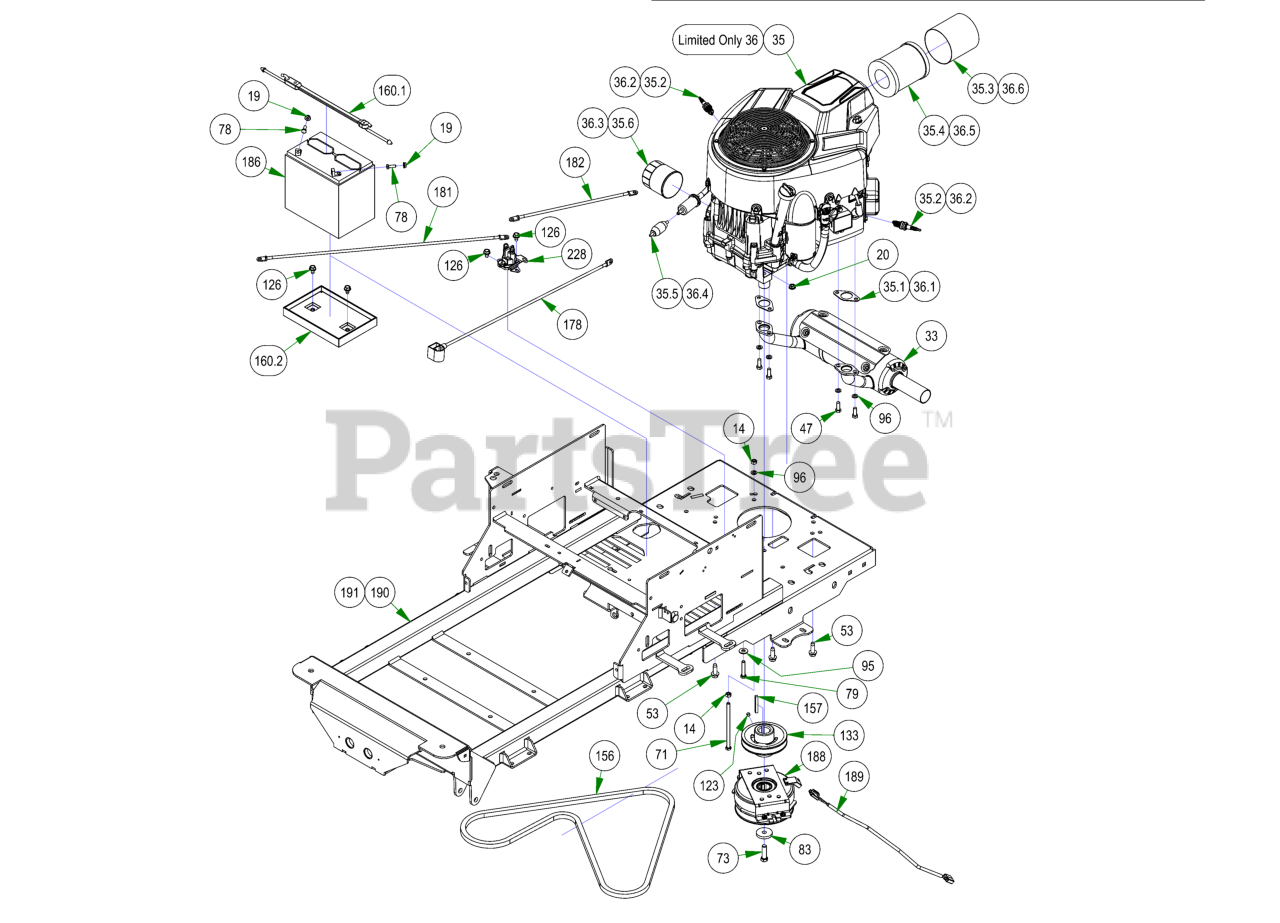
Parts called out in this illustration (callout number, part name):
14	5/16-18 HEX NUT ZINC
19	1/4-20 HEX SERRATED FLANGE NUT HARD/ZINC
20	5/16-18 HEX SERRATED FLANGE NUT HARD/ZINC
33	2017 Compact Outlaw Exhaust 810 Vanguard
35	Vanguard 25hp CXI with out Oil Filter ZT Elite
35.1	Exhaust Gasket
35.2	Spark Plug
35.3	pre-Cleaner for Vanguard CXI Engine
35.4	Air Filter for Vanguard CXI Engine
35.5	Universal Inline Fuel Filter
35.6	Oil Filter
36	Vanguard 27hp CXI with Out Oil Filter Maverick
36.1	Exhaust Gasket
36.2	Spark Plug
36.3	Oil Filter
36.4	Universal Inline Fuel Filter
36.5	Air Filter for Vanguard CXI Engine
36.6	pre-Cleaner for Vanguard CXI Engine
47	Torx Bolt-Exhaust
53	3/8-16 X 1-1/8HEX WASHER UNSLOT SERRATED (TRI-LOB) TRS
71	5/16-18 X 5-1/2 HEX CAP SCREW (GR.5) ZINC
73	7/16-20 X 1-1/2 HEX CAP SCREW (GR.8) w/ Patch
78	1/4-20 X 3/4 HEX CAP SCREW (GR.5) ZINC
79	5/16-18 X 1-3/4 HEX CAP SCREW (GR.5) ZINC
83	CLUTCH WASHER
95	5/16 USS FLAT WASHER (7/8 OD) ZINC
96	5/16 SPLIT LOCKWASHER ZINC
123	5/16-24 X 1/4 SOCKET SET SCREW (CUP PT) PLAIN
126	5/16-18 X 1/2 HWH unslot (F) tcs zinc
133	4 3/4 Motor Pulley
157	1/4 X 2 SQ MACHINERY KEY 1018 STL PLAIN
160	2023 Battery Hold Down Assembly Strap
160.1	2023 Rubber Battery Hold Down Strap
160.2	Battery Tray
178	24 inch Black Cable – MZ/ZT
181	24" Red Battery Cable
182	12 in red battery cable
186	SP-35 Battery
189	Clutch Pigtail
190	2023 ZT Elite Frame- Painted
191	2023 ZT Elite Frame- Painted
